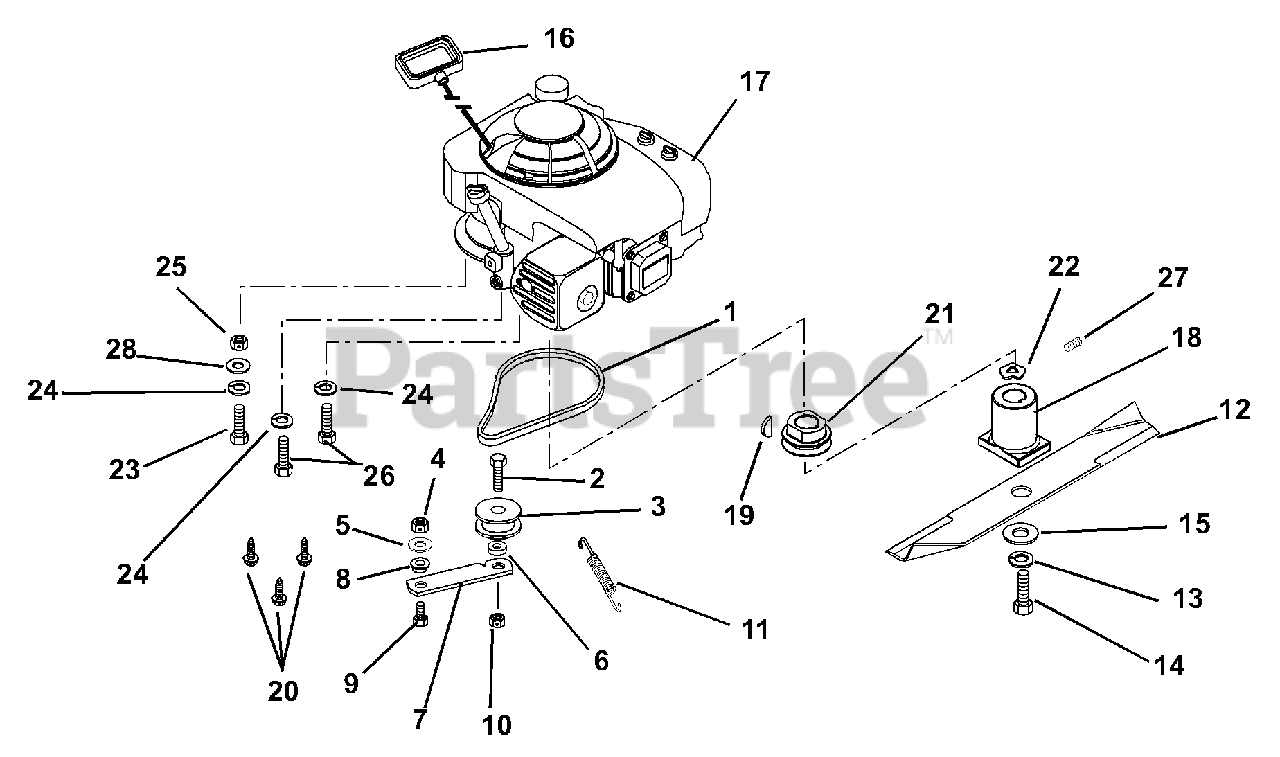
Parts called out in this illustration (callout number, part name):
1	V-BELT, 3L-COGGED
2	@BLT-HEX .44-14X1.50 GR5 YWZC
3	IDLER-FLAT 1.75 X .47
4	@NUT-LK-CTR .31-18 YWZC
5	@WSHR-FL-STL.344X.688X.065YWZC
6	BSHG-SLV .469 X .750 X .430
7	IDLER ARM
8	BSHG-FLG .325X.501X.250X1.120
9	@BLT-HEX .31-18X.75 GR5 YWZC
10	@NUT-LK-CTR .44-14 YWZC
11	SG-TENS .043X.44X3.31 WLD 5.8
12	21" MOWER BLADE
12	BLADE, 21" MOWER TUNGSTEN
13	@WSHR-LK .38X.094 REG YWZC
14	BLT-HEX .38-24 X 2.00 GR8 YWZC
15	WSHR-FL-STL .390X1.5X.125 YWZC
16	HANDLE, RECOIL START
17	ENGINE, B&S QUANTUM 6.5HP
17	ENGINE - HONDA 5.5 HP OHV
17	ENGINE, KAWASAKI 6.0 CONSUMER
17	6.0 HP KAWI U.S. COMMERICIAL
18	ADAPTER-SINTERED IRON LM
18	ADAPTER - BLADE HUB
19	KEY-WDRF .156X.625X.25 SAE 6
20	@SCR-TAP .38-16X1.00 HWH TR YZ
21	PULLEY-SINTERED IRON LM
21	PULLEY - UNV DRIVE - STEEL
22	WASHER-WAVE .885X1.311X.125
23	BLT-HEX .31-24X1.50 GR5 YWZC
24	@WSHR-LK .31X.078 REG YWZC
25	NUT-HEX .312-24 YWZC
26	BLT-HEX .31-24X1.00 GR5 YWZC
27	SCR-SET .31-18X.38 SKHCUPDL
28	@WSHR-FL-STL.344X.688X.065YWZC
